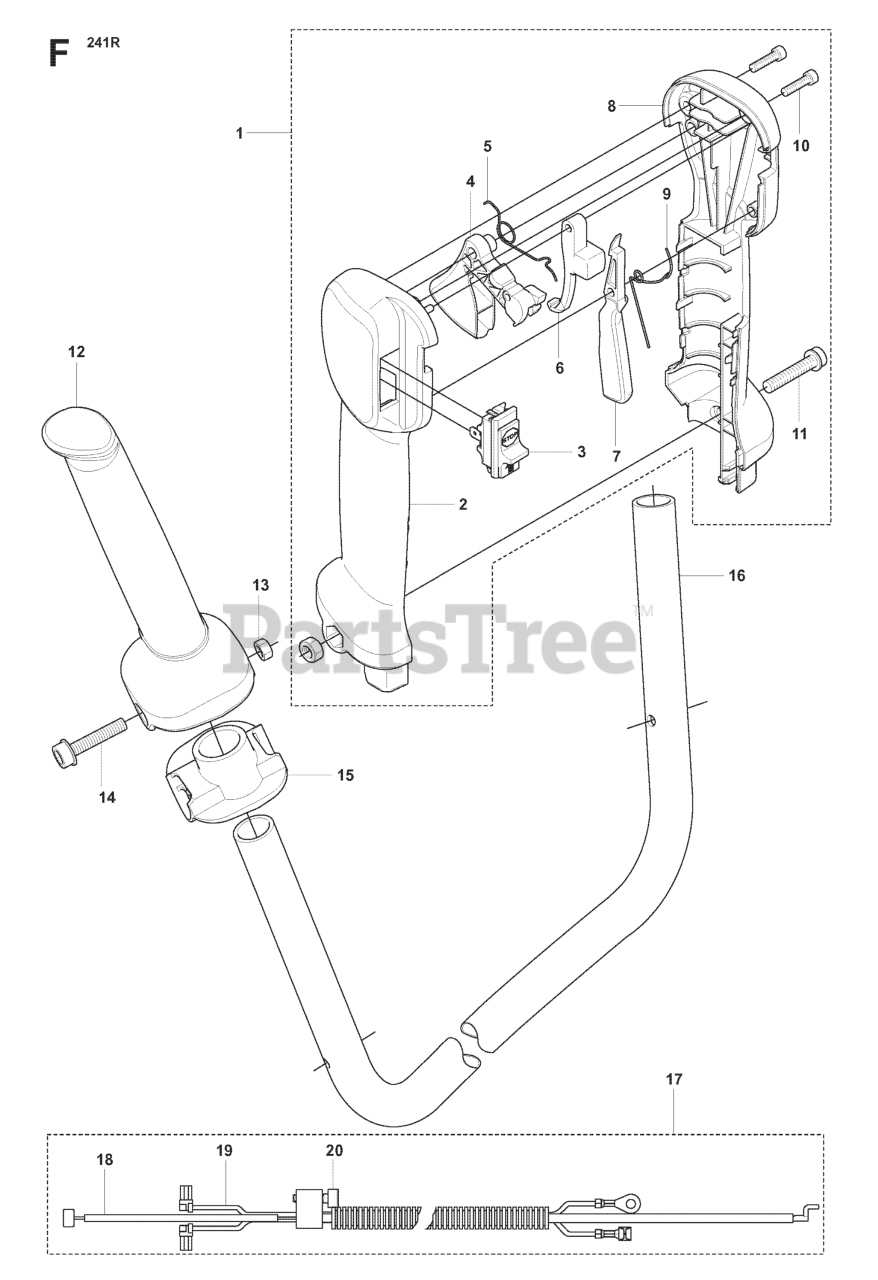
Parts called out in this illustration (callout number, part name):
1	HANDLE SYSTEM ASSY.
3	STOP BUTTON
4	THROTTLE TRIGGER
6	LOCKOUT STARTER THROTTLE
7	THROTTLE LOCK
11	SCREW
17	WIRING KIT COMPLETE
18	THROTTLE WIRE
19	SHORT CIRCUIT CABLE
